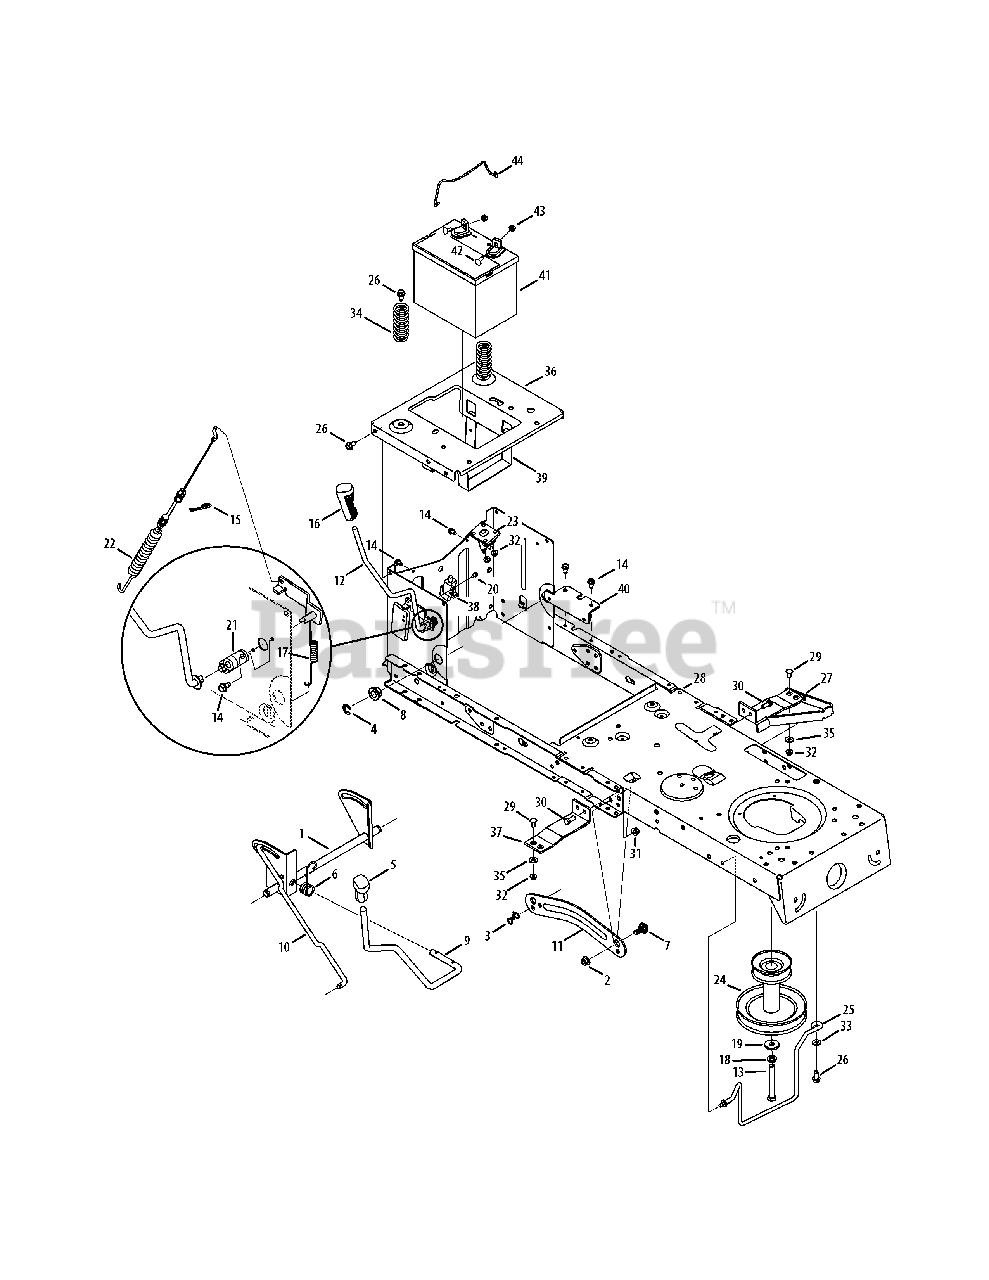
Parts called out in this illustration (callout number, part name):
1	Shaft, Lift
2	Nut, Hex Flange Insert Lock, 3/8-16
3	Bow-Tie Pin, 91, RH
4	E-ring, .625 Shaft
5	Grip, Handle
6	Spring, Lift Handle Torsion
7	Bolt, Shoulder, .625 x .175:3/8-16
8	Bearing, Hex Flange,
9	Handle, Lift
10	Lift Rod, 13.68
11	Arm, Deck Lift RH
11	Arm, Deck Lift LH
12	PTO Handle Assembly
13	Screw, Hx. Hd., 7/16-20 x 3.25
14	Screw, Hd. Tapp, 1/4-20 x .5
15	Click Pin
16	Handle Grip
17	PTO Spring, Extension
18	Washer, Flat, 7/16
19	Washer, Flat, .450 x .250 x .164
20	Shoulder Screw, #10-32 x .500
21	PTO Bearing
22	Deck Engagement Cable
23	12v. Solenoid
24	Engagement Pulley
25	Belt Keeper Rod Assembly
26	Screw, Hd. Tapp, 5/16-18 x .75
27	Support Bracket Assembly
28	Rider Frame Assembly
29	Carriage Screw, 1/4-20 x .62
30	Screw, Hx. Hd., 5/16-18 x .75
31	Nut, Hex Flange Insert Lock, 5/16-18
32	Nut, Hex Flange Insert Lock, 1/4-20
33	Flat Washer, .406 x .875 x .059
34	Compression Spacer, 1.314 x 2.55
35	Flat Washer, .28 x .74 x .063
36	Seat Bracket Frame
37	Running Board Bracket
38	Interlock Switch
39	Battery Bracket
40	Frame Brace Bracket
41	Battery
42	Screw, Shoulder, .250 x .150
43	Nut, Sems, 1/4-20
44	Battery Rod
